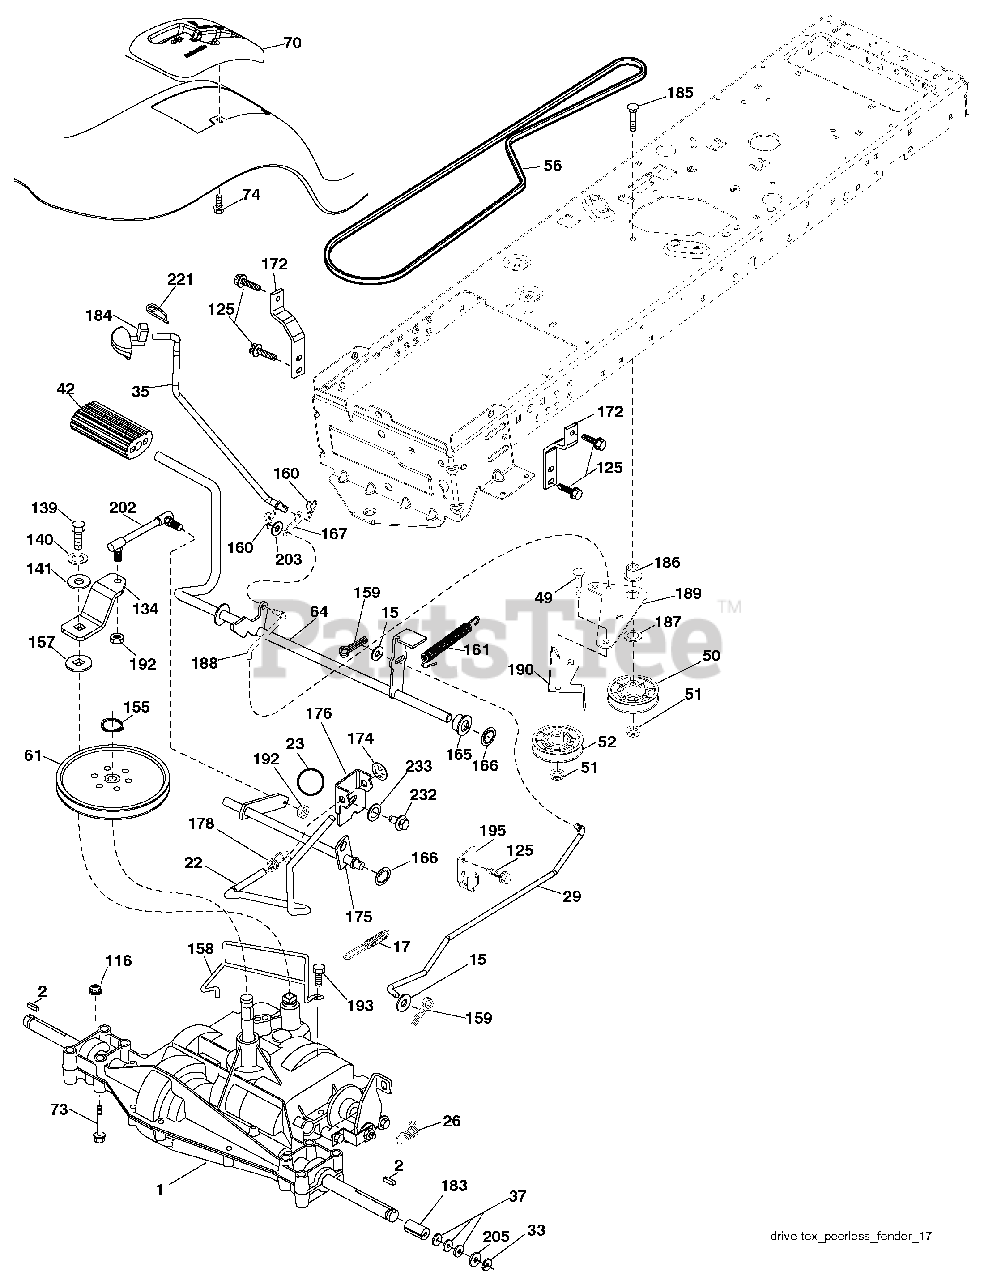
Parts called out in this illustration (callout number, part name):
2	Key Square
15	Washer 13/32 x 13/16 x 16 Ga.
17	Spring, Brake
22	Rod Shift
23	Spring Brake RTN
29	Rod, Brake
33	Ring E
35	Rod, Brake, Park
37	Washer 25/32 x 1-1/4 x 16 Ga.
42	Cover, Foot Pedal
49	Bolt
50	Pulley Idler Flat
51	Lock Nut 3/8-16
52	Idler V-Groove
56	V-Belt, Drive
61	Pulley Transaxle
64	Shaft Asm. Pedal Brake Control
70	Console
73	Bolt 5/16-18 Gr. 5
74	Screw 1/4 x 1/2
116	Nut Lock Hex Flange 5/16-18
125	Screw 5/16-18 x 3/4
134	Arm Shift
139	Bolt 1/4-20 unf Gr. 8 w/Patch
140	Washer Lock Hvy Helical 1/4
141	Washer 9/32 x 3/4 x 10 Ga.
155	Ring Retainer
157	Washer Plate Shf
158	Keeper T/A
159	Pin Cotter 1/8 x 3/4
160	Retainer Clip
161	Spring, Return, Clutch
165	Busing Shaft Brake Hand Control
166	Nut Push .625
167	Latch Brake Parking
172	Strap Torque LH
174	Nut Push
175	Shaft Asm Shift
176	Arm Clevis Rod Shift
178	Spring Shift
183	Spacer, Axle
184	Handle Parking Brake
185	Bolt
186	Spacer Retainer
187	Washer
188	Link Clutch Ground Drive
189	Bellcrank Ground Drive
190	Keeper Bellcrank Ground Drive
192	Nut Lock Center 1/4-28
193	Screw 5/16-18 x 3/4
195	Bracket Brake Rod
202	Link Shift
203	Washer 11/32 x 11/16 x 16 Ga.
205	Washer 25/32 x 1-5/8 x 16 Ga.
221	Retainer Spring Clip Handle
232	Bolt 7/16-14 x 1 Gr. 5
233	Washer Serrated
